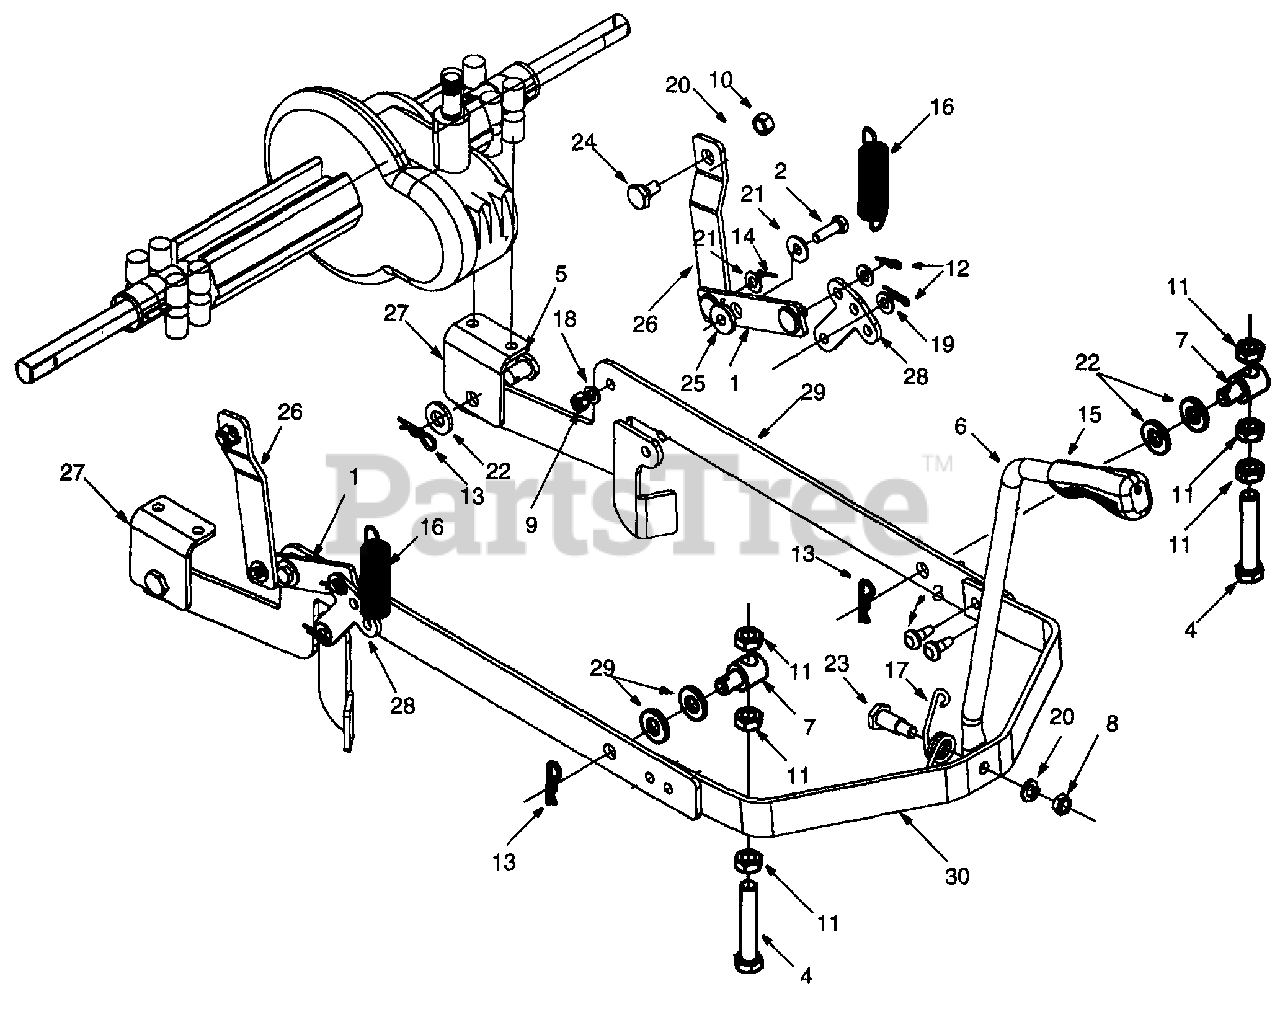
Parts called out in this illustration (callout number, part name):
4	Hex Bolt 1/2-13 X 2.75 Gr. 5 Special
5	Lift Bracket Pin
6	Lift Rod
7	Ferrule
8	Jam Nut 3/8-16 Gr. 5
9	Hex Nut 5/16-18
10	Hex Cent. Lock Nut 3/8-16
11	Hex Jam Nut 1/2-13 Gr. 5
12	Cotter Pin
13	Cotter Pin
14	Cotter Pin
15	Handle Grip
16	Extension Spring
17	Torsion Spring
18	Lock Washer 5/16
19	Flat Washer .385 I.D. x .620 O.D.
20	Lock Washer
21	Flat Washer 5/16
22	Flat Washer
23	Shoulder Screw
24	Shoulder Screw
25	Shoulder Spacer
